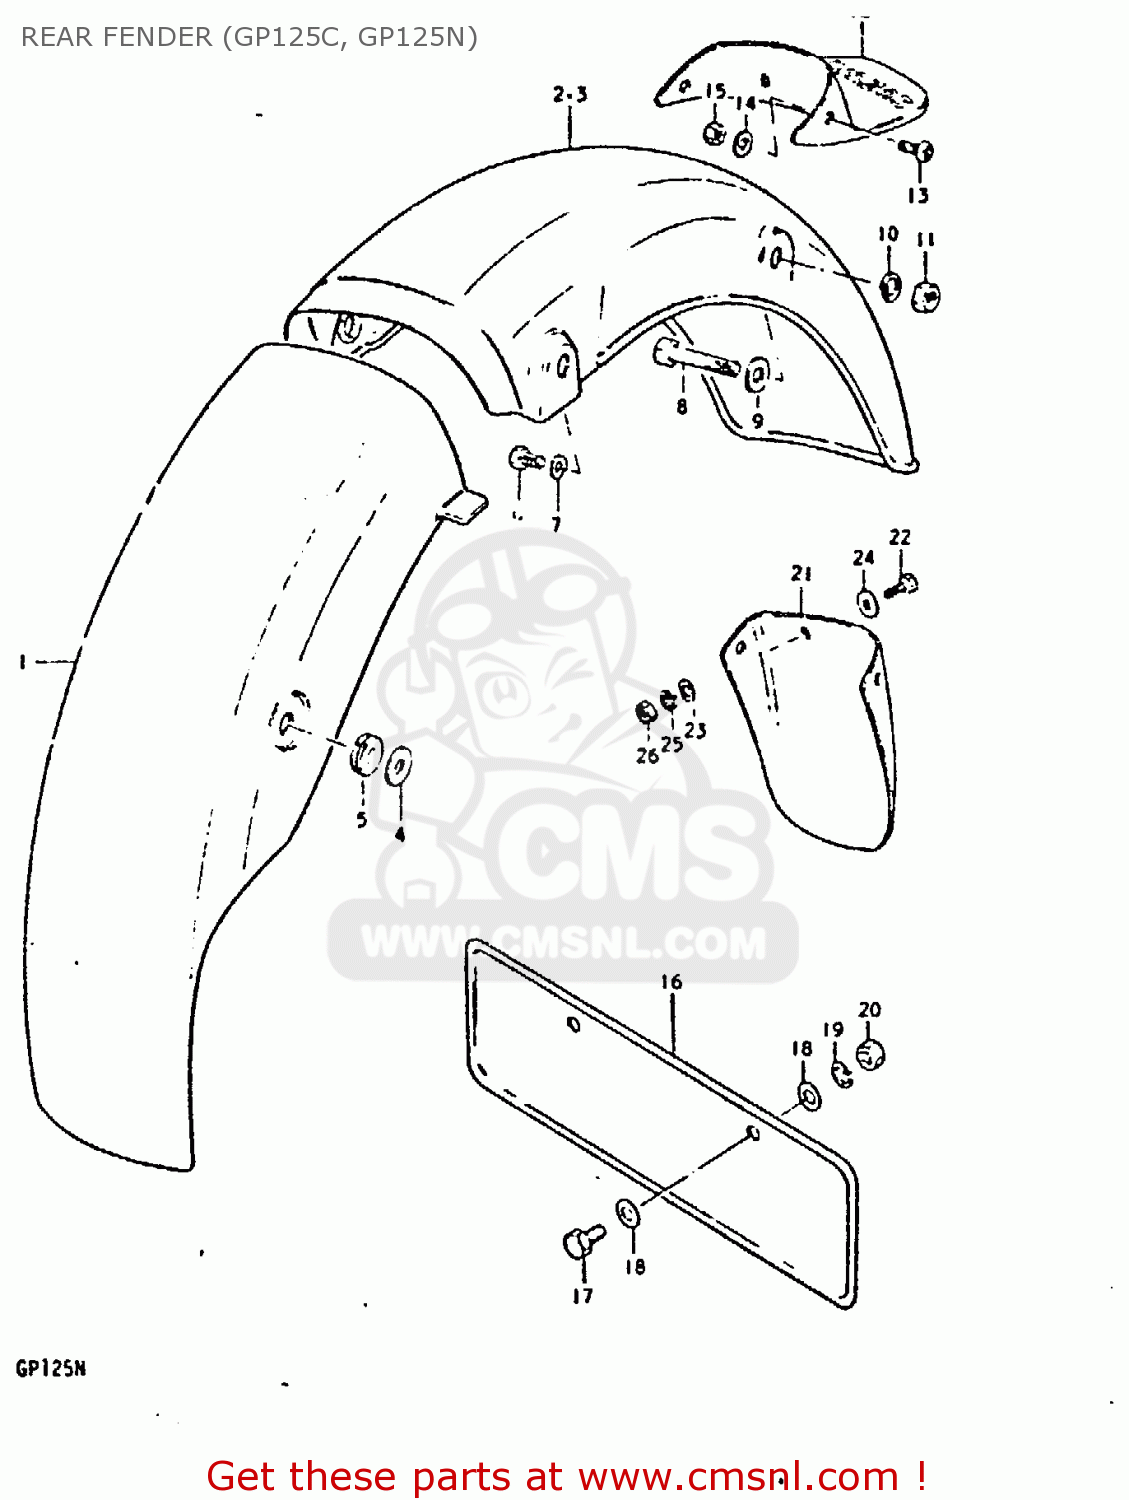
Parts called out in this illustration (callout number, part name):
1	BODY, REAR FENDER FRONT
2	BODY, REAR FENDER REAR
4	WASHER
5	CUSHION
6	BOLT
7	LOCK WASHER
8	BOLT 8X45
10	LOCK WASHER
